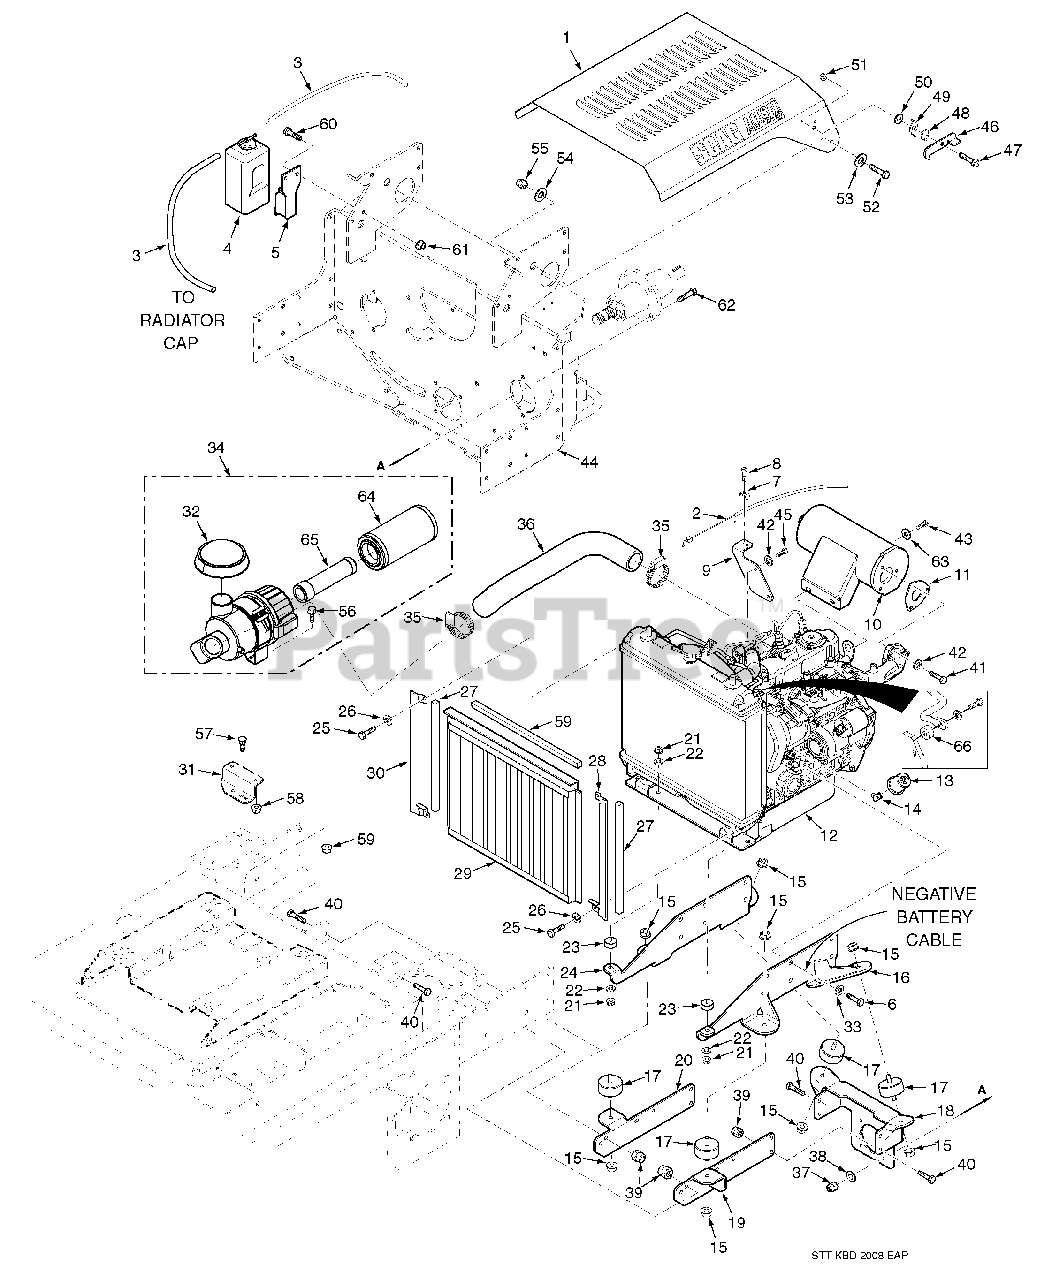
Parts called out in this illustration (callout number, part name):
1	Hood Assembly
2	Throttle Cable
3	Hose, Over Spill Bottle
4	Over Spill Bottle
5	Mounting Bracket, Over Spill Bottle
6	Bolt, Metric Hex Hd. M10-1.25 x 25mm
7	Clamp
8	Screw, Self Tapping
9	Bracket, Control Mount
10	Muffler, Kubota
11	Gasket, Muffler
12	Engine, Kubota
13	Oil Pressure Sender
14	Elbow, 45 Deg.
15	Nut, Serr. Flng. 5/16-18
16	Mounting Bracket Weldment LH
17	ISO Mount
18	Plate, Rear Engine Mount
19	Plate, Engine Mount LH
20	Plate, Engine Mount RH
21	Nut, Metric Hex M8-1.25mm
22	Lockwasher, 5/16" Spring
23	Rubber ISO Mount, Radiator
24	Mounting Bracket Weldment RH
25	Capscrew, Metric M6-1.0 x 16mm
26	Lockwasher, 1/4" Spring
27	Foam, Radiator Screen
28	Debris Screen Track LH
29	Debris Screen Assembly
30	Debris Screen Track RH
31	Bracket, Air Cleaner Mount
32	Rain Cap (Enginaire p/n 68381)
33	Lockwasher, 7/16" Spring
34	Air Filter Assembly (Enginaire p/n 68665)
35	Clamp, 2-1/4" Max. Dia.
36	Hose, Air Intake
37	Nut, Elastic Stop 5/16-18 Grd. 8
38	Lockwasher, 5/16" Spring
39	Nut, Elastic Stop 3/8-16
40	Bolt, Hex Hd. 3/8-16 x 1"
41	Bolt, Metric Hex Hd. M8-1.25 x 30mm
42	Lockwasher, 5/16" Spring
43	Bolt, Metric Hex Hd. M8-1.25 x 25mm
44	Pump Mounting Plate Weldment (Kubota)
45	Bolt, Metric Hex Hd. M8-1.25 x 20mm
46	Latch, Hood
47	Bolt, Shoulder 5/16-18 x 1/2"
48	Spring, Hood Latch
49	Lock, Hood Latch
50	Flatwasher, 3/8 (.391 x .938 x .105")
51	Nut, Center Lock 5/16-18
52	Bolt, Hex Hd. 3/8-16 x 1-3/4"
53	Flatwasher, 3/8 (.391 x .938 x .105")
54	Flatwasher, 3/8 (.406 x 1.50 x 7 Ga.)
55	Nut, Elastic Stop 3/8-16
56	Bolt, Hex Hd. Serr. Flng. 5/16-18 x 3/4"
57	Bolt, Carriage 5/16-18 x 3/4"
58	Nut, Serr. Flng. 5/16-18
59	Foam, Radiator Screen Upper
60	Bolt, Hex Hd. Serr. Flng. 5/16-18 x 3/4"
61	Nut, Serr. Flng. 5/16-18
62	Bolt, Hex Hd. 5/16-18 x 1-3/4" Grd. 8
63	Flatwasher, SAE 5/16 (.344 x .688 x .065")
64	Air Filter, Outer (Enginaire p/n 68300)
65	Air Filter, Inner (Enginaire p/n 68340)
66	Spacer, Radiator
